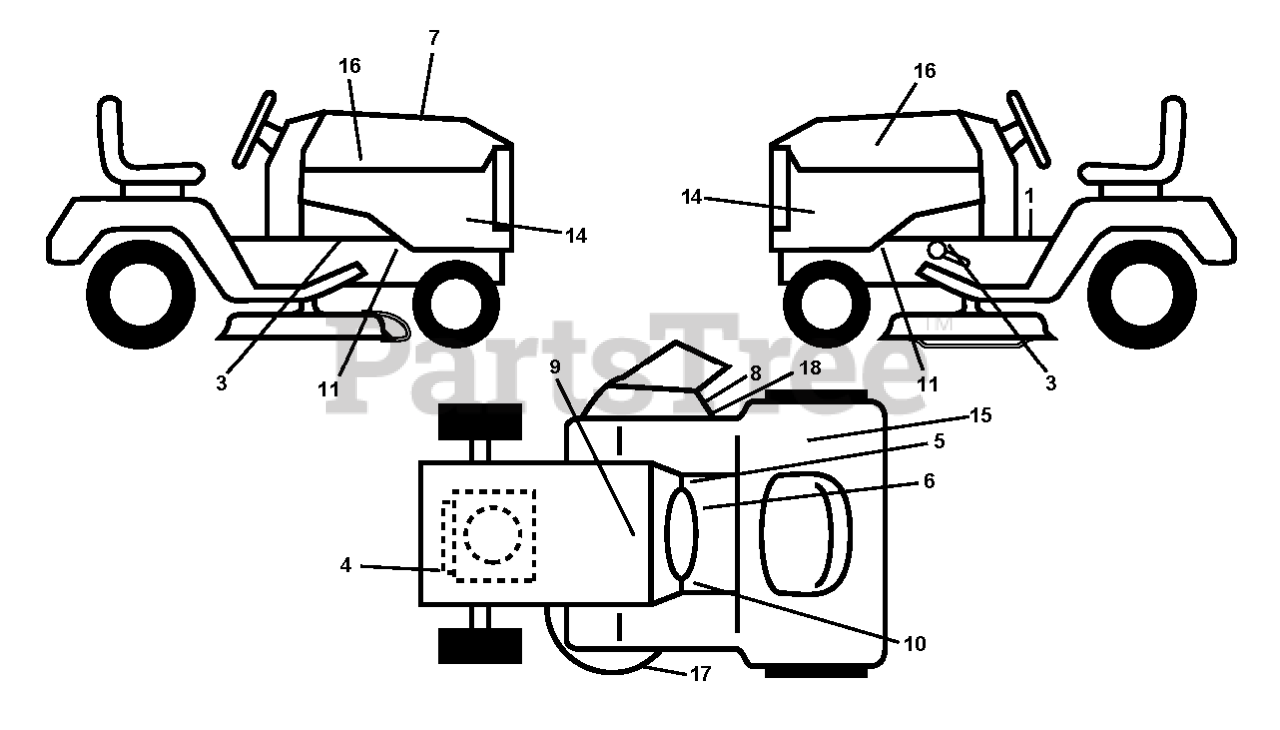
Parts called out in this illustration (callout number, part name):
1	LABEL
4	DECAL
5	DECAL PARK BRAKE
6	DECAL
7	DECAL RPL KO
8	DECAL.INTERNATIONL.CUTFINGER
9	DECAL BTRY SYMBOLS
10	DECAL
14	DECAL PNL SD.
15	DECAL.FENDER
16	RP.DECAL.BADGE.170MM.TEXTLOGO
17	DECAL.MOWER.SCH.48/54
18	DECAL, DEFLECT WARNING
